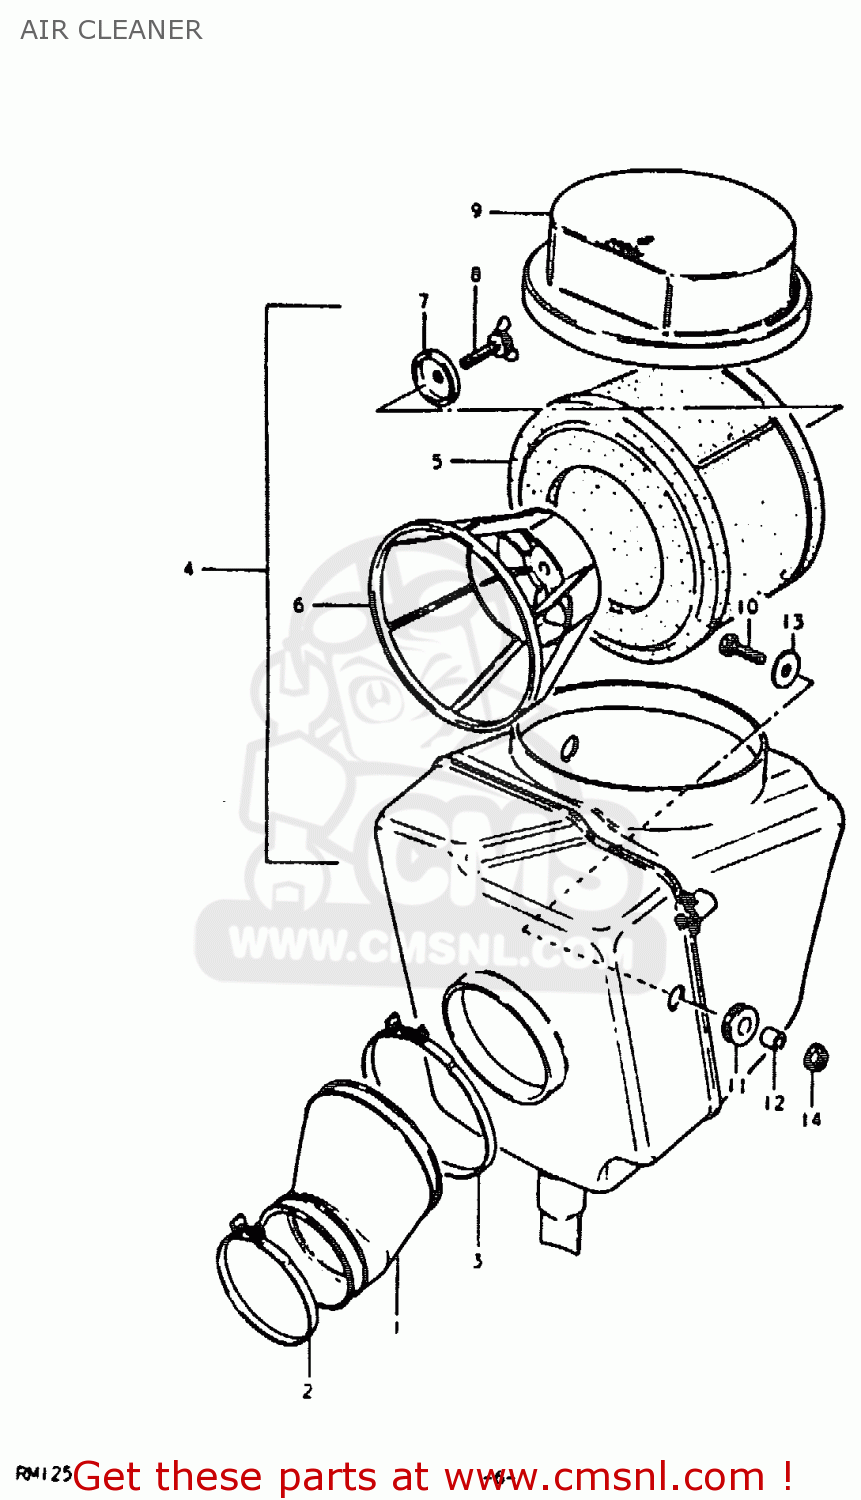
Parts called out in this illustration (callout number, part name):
1	TUBE,AIR CLEANER OUTLET
2	CLAMP
3	CLAMP
4	CLEANER ASSEMBLY,AIR
5	FILTER
6	HOLDER
7	HOLDER,FILTER
8	WING BOLT,AIR CLEANER
9	CAP,AIR CLEANER
10	BOLT
11	CUSHION
12	SPACER (6.1X9X9)
13	WASHER (6.5X20X1.2)
14	NUT
